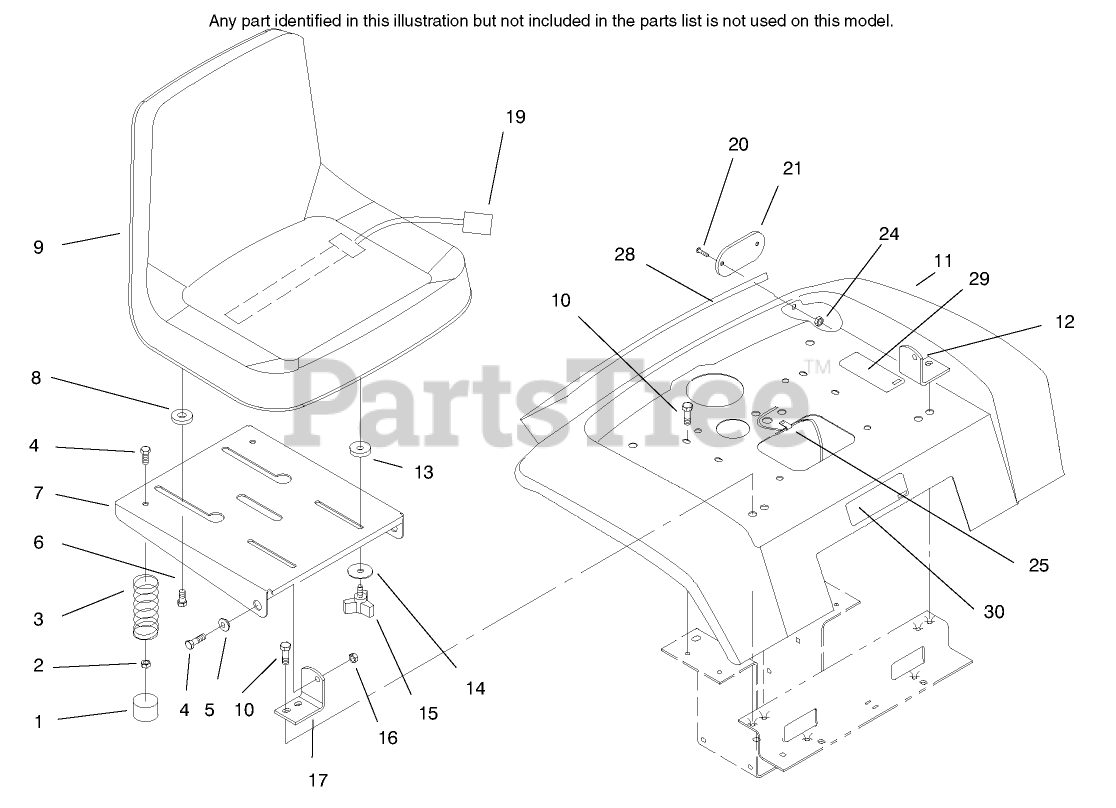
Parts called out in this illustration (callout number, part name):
1	CAP-PROTECTOR
2	NUT-LOCK, NI
3	SPRING-COMPRESSION
4	SCREW-HH
5	BUSHING
6	BOLT-SHOULDER
8	SPACER-NYLON
12	BRACKET-PIVOT, LH
13	SPACER-NYLON
14	WASHER
16	NUT-LOCK, NI
17	BRACKET-PIVOT, RH
19	SWITCH-SEAT
20	SCREW-PPH
24	NUT-LOCK, NI
30	DECAL - USA
